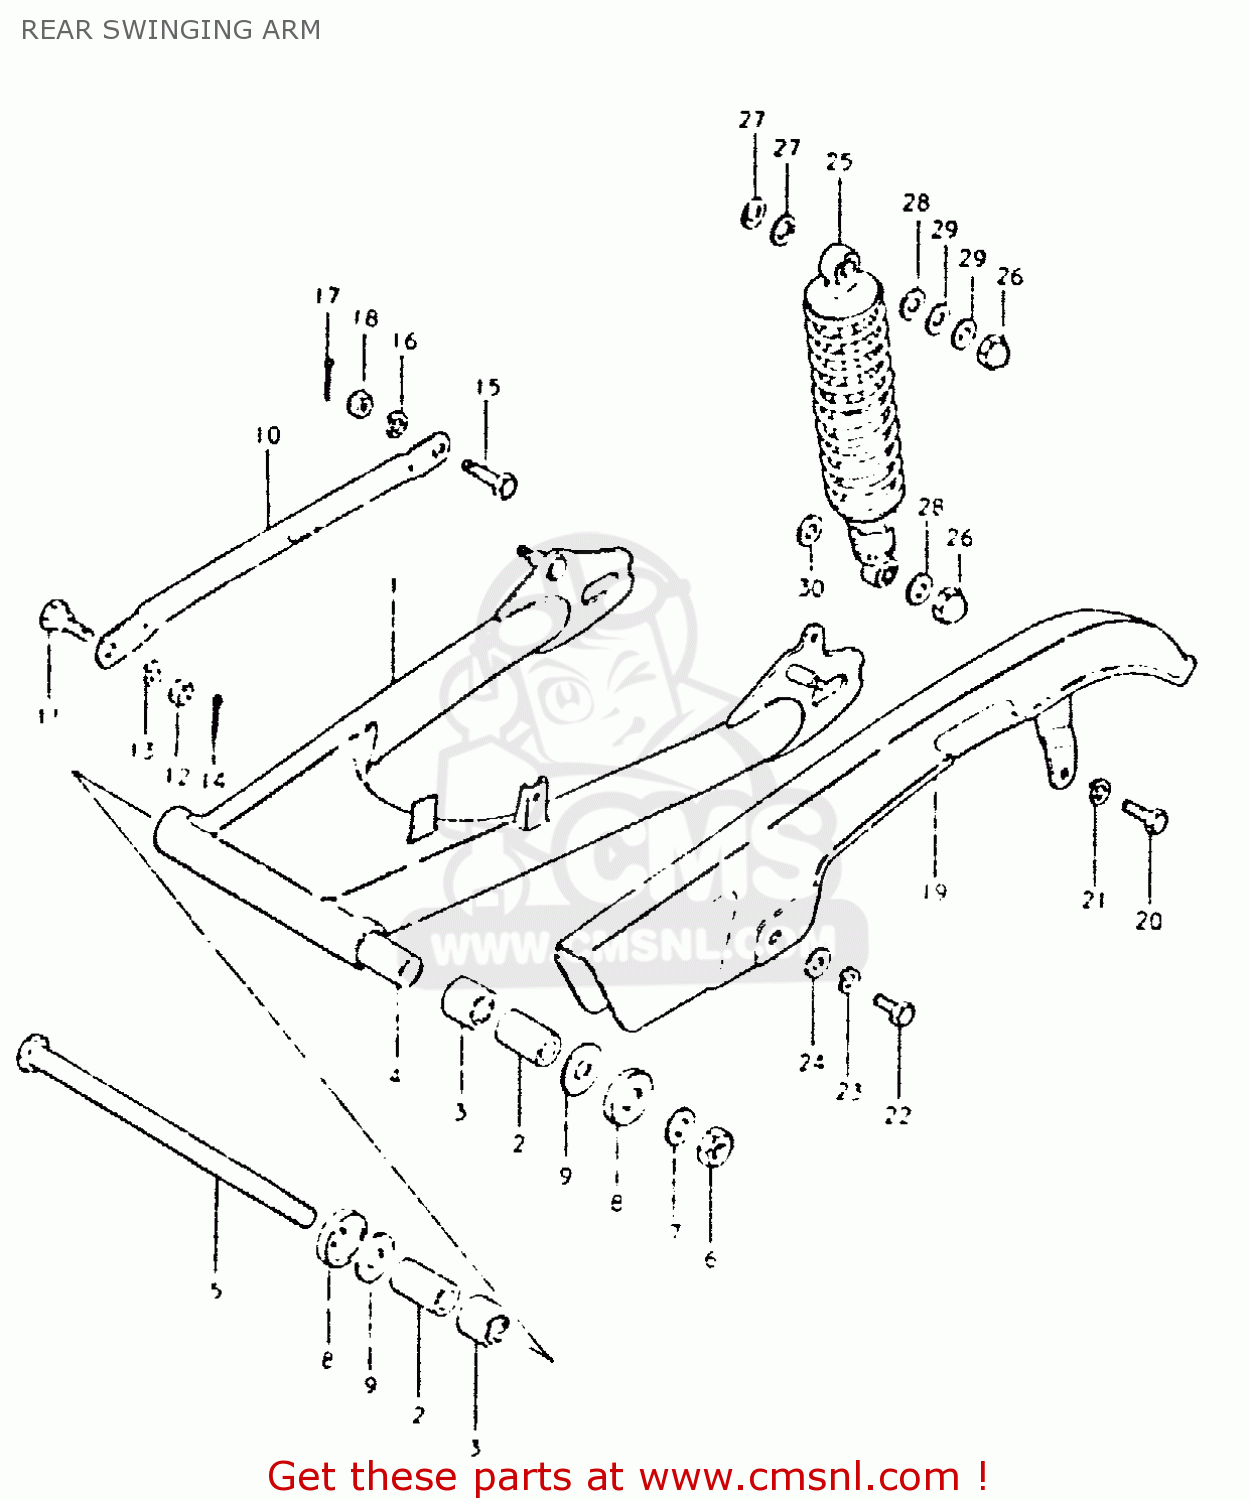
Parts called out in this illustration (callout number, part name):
1	SWING ARM ASSEMBLY,REAR
2	SPACER,RR SWGARM PIVOT
3	BEARING(22X29X30)
4	SPACER,SWINGINGARM CTR
5	SHAFT,REAR SWING ARM
6	NUT 14MM
7	WASHER
8	CVR,RR SWGARM DUST SEAL(OD:40)
9	WASHER(14.2X34X1)
10	TORQUE LINK,REAR
11	BOLT(10X24.5)
12	NUT
13	LOCK WASHER
14	PIN
15	BOLT(10X31)
16	LOCK WASHER
17	PIN
18	NUT
19	CASE,CHAIN
20	BOLT, UPPER
21	LOCK WASHER
22	BOLT
23	LOCK WASHER
24	WASHER
25	ABSORBER ASSEMBLY,REAR SHOCK
26	NUT, LOWER LH
27	WASHER
28	WASHER
29	WASHER(10.5X24X3.2)
30	WASHER (12.5X24X1.6)
